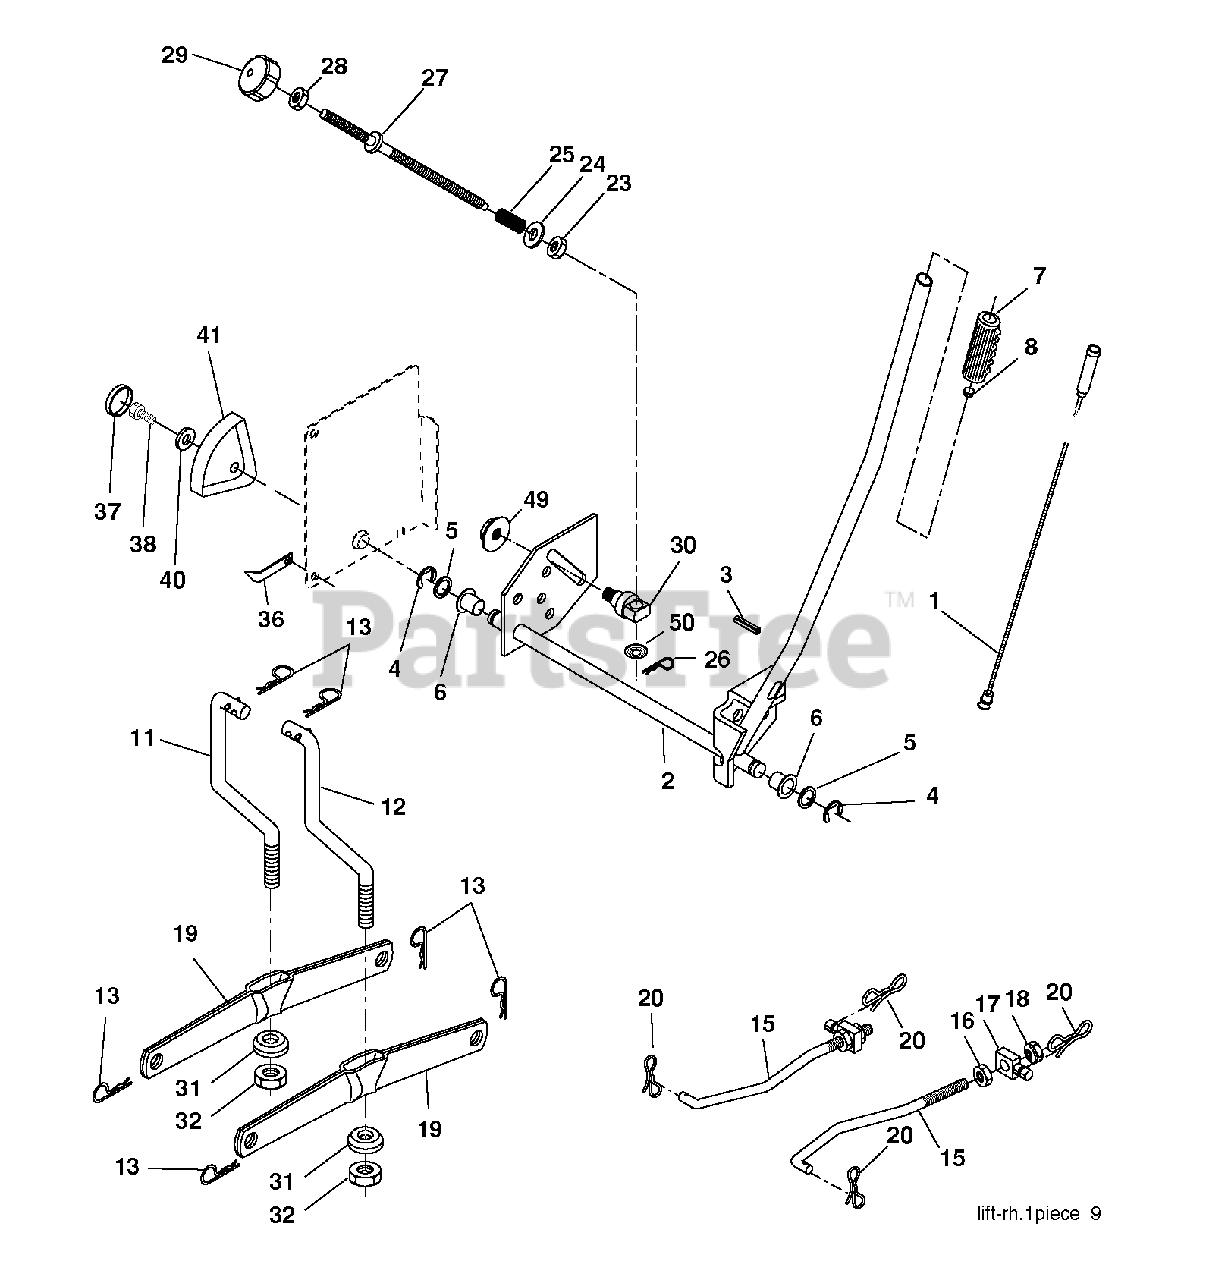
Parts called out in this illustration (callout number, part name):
1	PLUNGER.ASM.LIFT.LVR.BLK.17.32
2	SHAFT ASM R HANDLE
3	PIN GROOVE
4	RETAINING RING LT
6	BEARING.NYLON
7	GRIP HANDLE
8	PLUNGER BUT KIT
11	LINK LIFT LH
12	LINK LIFT RH
13	RETAINER-SPRNG RB
15	LINK.SUSPENSION.FRONT
16	NUT
18	NUT
19	ARM.REAR.SUSPENSION
20	PIN.COTTER.7/16.BOW TI
25	SPRING**
26	RETAINER CLIP
27	ROD ADJ LIFT
28	NUT
29	KNOB INF 3/8-16
31	BEARING.PIVOT.LIFT
32	NUT CROWNLOCK 3/8-24
36	POINTER, HEIGHT INDICATOR
37	PLUG,HOLE
38	SCREW 5/16-18X1
41	HEIGHT INDICATOR
49	NUT.HEX.FLANGE.3/8-16.LOCKNUT
50	NUT PUSH M
